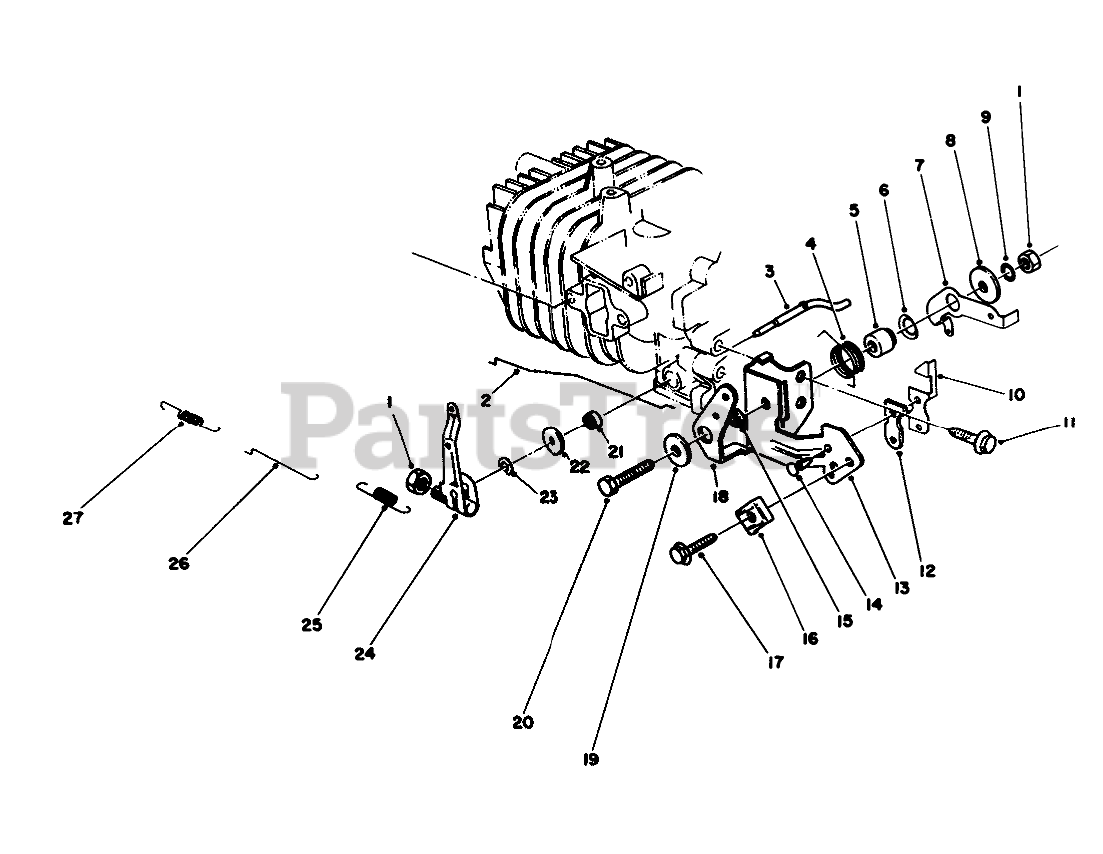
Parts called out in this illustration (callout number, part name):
2	CHOKE ROD
3	Shaft-Govemor
4	SPRING-CHOKE LEVER
5	Gov Lever Spacer
6	Washer-Gov. Spring Lever
7	LEVER-SPRING, GOVERNOR
8	WASHER
9	LOCKWASHER
10	TERMINAL-KILL SWITCH
12	INSULATOR-KILL SWITCH
13	BRACKET-THROTTLE, CONTROL
14	KILL SWITCH RIVET
15	SPACER-CHOKE LEVER
16	CLAMP
18	LEVER-CONTROL, CHOKE
19	WASHER
21	SEAL-OIL
22	WASHER
23	E-RING
24	GOVERNOR ARM
25	SPRING-GOVERNOR
26	ROD-CARBURETOR
27	SPRING
